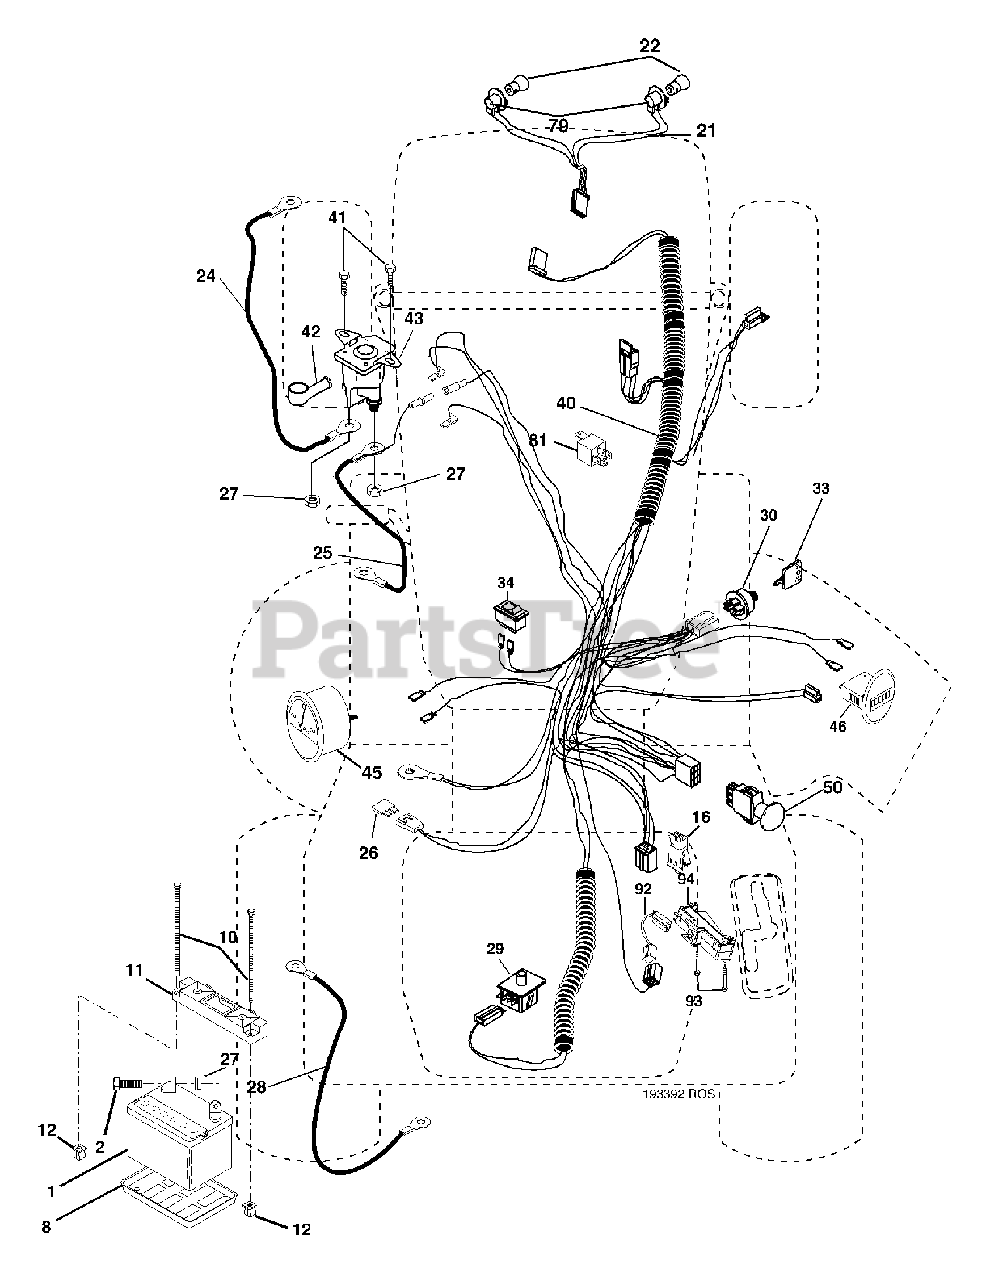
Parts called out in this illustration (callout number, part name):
1	Battery
2	Bolt Hex Head 1/4-20 x 3/4
8	Tray, Battery
10	Bolt, Battery Front 1/4-20 x 7.5 Zinc
11	Holddown Battery Front Mount
12	Nut, Push Nylon 1.4" Battery Front
16	Switch Interlock Push-In
21	Harness Socket Light w/4152J
22	Bulb Light
24	Cable 6 Ga. Red 12.5 w/16 Wire
25	Cable
27	Nut Keps Hex 1/4-20
28	Cable Bolt Ground
29	Switch, Seat
30	Switch, Ign
34	Switch Light/Reset B/B/Red
40	Harness Ign.
41	Screw THD Cut 1/4-20 x 1/2
42	Cover, Terminal Red
43	Solenoid
50	Switch, PTO
79	Bulbholder Asm
92	Harness Pigtail Reverse Switch
93	Screw 10-14 x 2.0
94	Modual Reverse ROS
